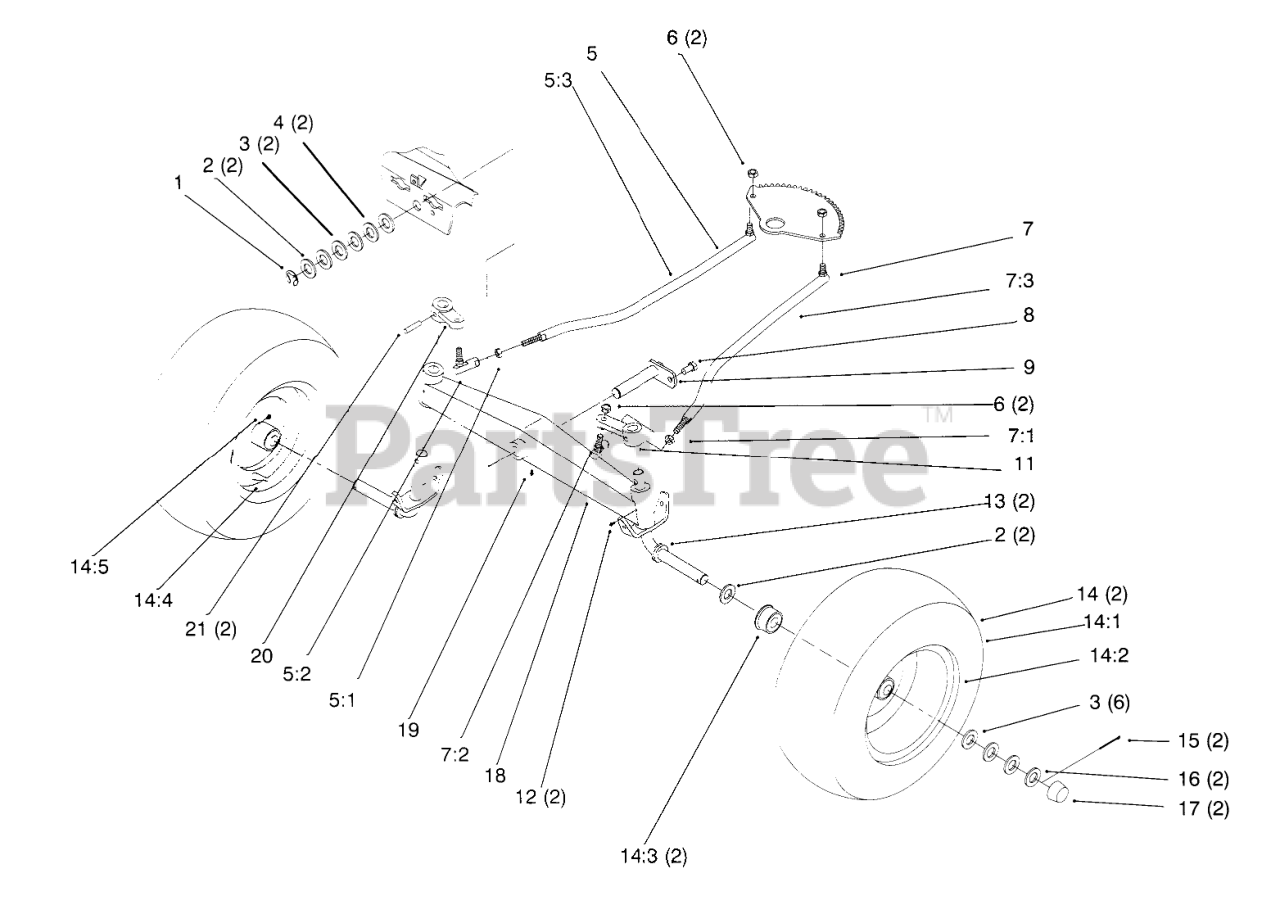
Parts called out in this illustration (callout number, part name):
1	E-RING
2	WASHER-SHIM
3	WASHER
4	Washer
5	LINKAGE-STEERING, RH
5:1	Nut-HJ
5:2	BALL-JOINT
5:3	Ball Link ASM
7	LINKAGE-STEERING, LH
7:1	Nut-HJ
7:2	BALL-JOINT
7:3	Ball Link ASM
8	SCREW-HWH, TAPTITE
9	PIN-AXLE
11	Arm-Front Spindle
12	FITTING-GREASE
13	SPINDLE
14	Wheel AND Tire ASM
14:1	Tire (16 x 6.5-8) 2-Ply -2 Wheel Axel
14:2	Wheel
14:3	BEARING-WHEEL
14:4	VALVE
14:5	ZERK-GREASE
15	PIN-COTTER
16	WASHER-PLAIN
17	CAP-HUB
18	AXLE-FRONT
19	FITTING-LUBE, 45 DEG
20	Arm-Front Spindle
